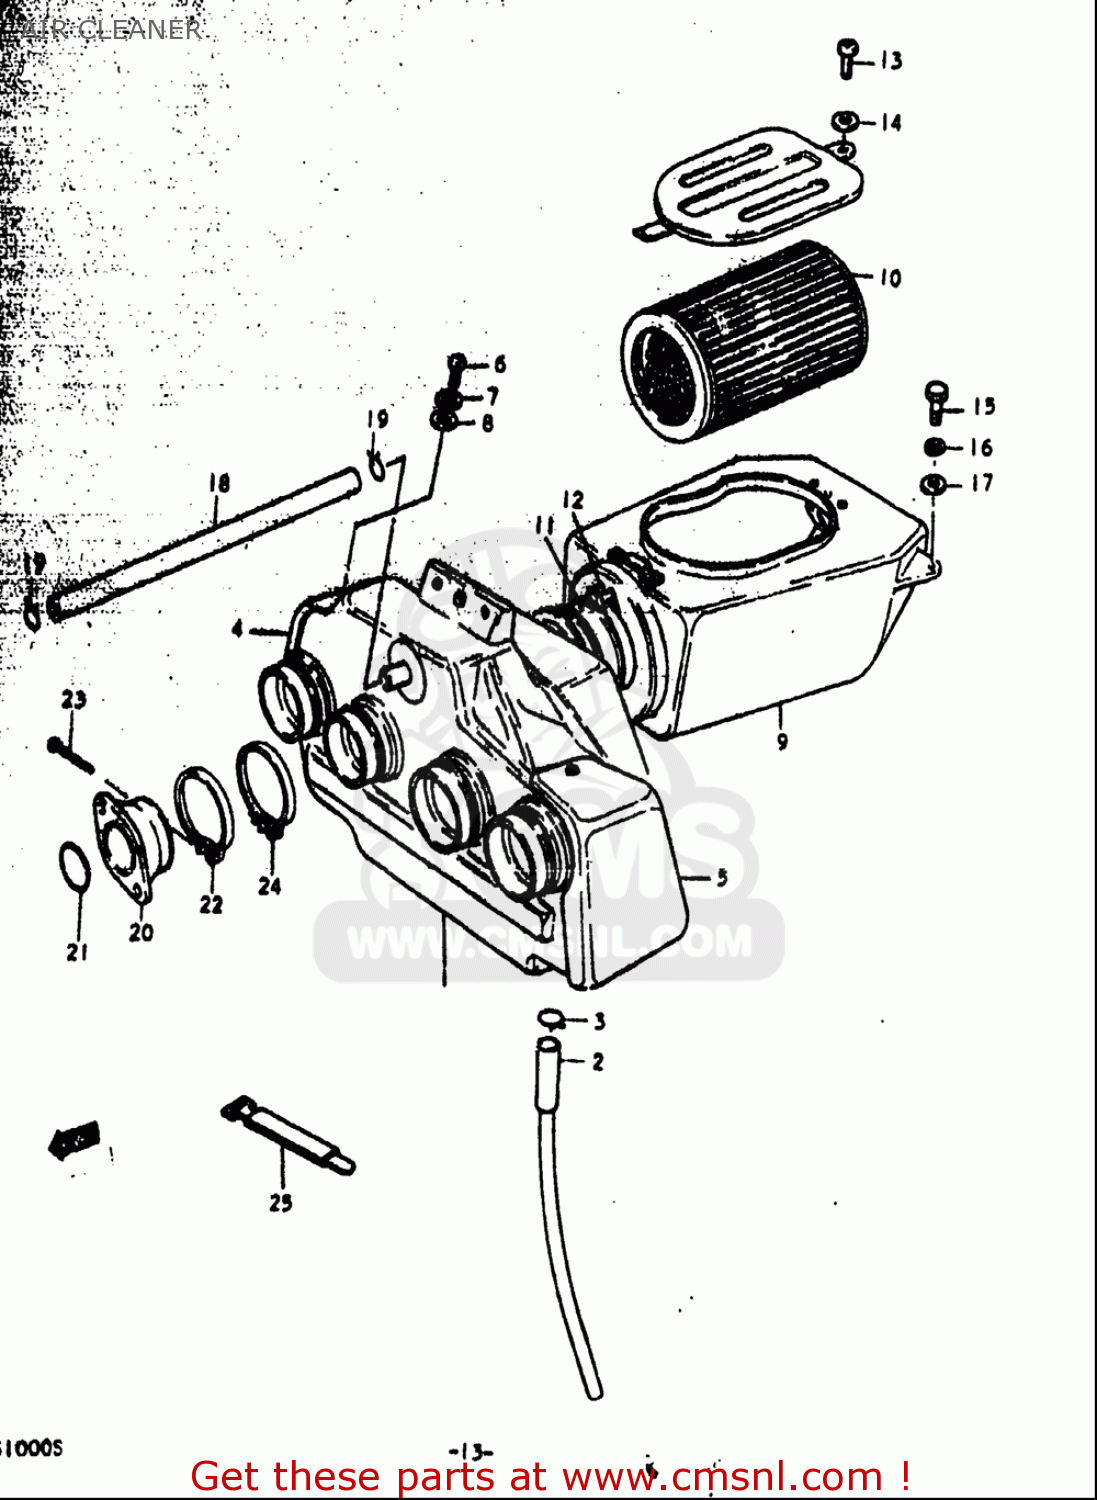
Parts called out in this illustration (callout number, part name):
2	TUBE,DRAIN
3	CLIP
6	SCREW
7	WASHER,LOCK
8	WASHER
9	CASE ASSEMBLY,AIR CLEANER
10	FILTER,AIR CLEANER
11	HOSE,AIR CLEANER
12	BAND
13	SCREW
14	WASHER
15	BOLT
16	WASHER,LOCK
17	WASHER
18	HOSE(11X15X2000)
19	CLIP
20	PIPE,INTAKE
21	O RING(D:2.4,ID:31.7)
22	CLAMP
23	SCREW
24	CLAMP
25	CLAMP(L:120)
